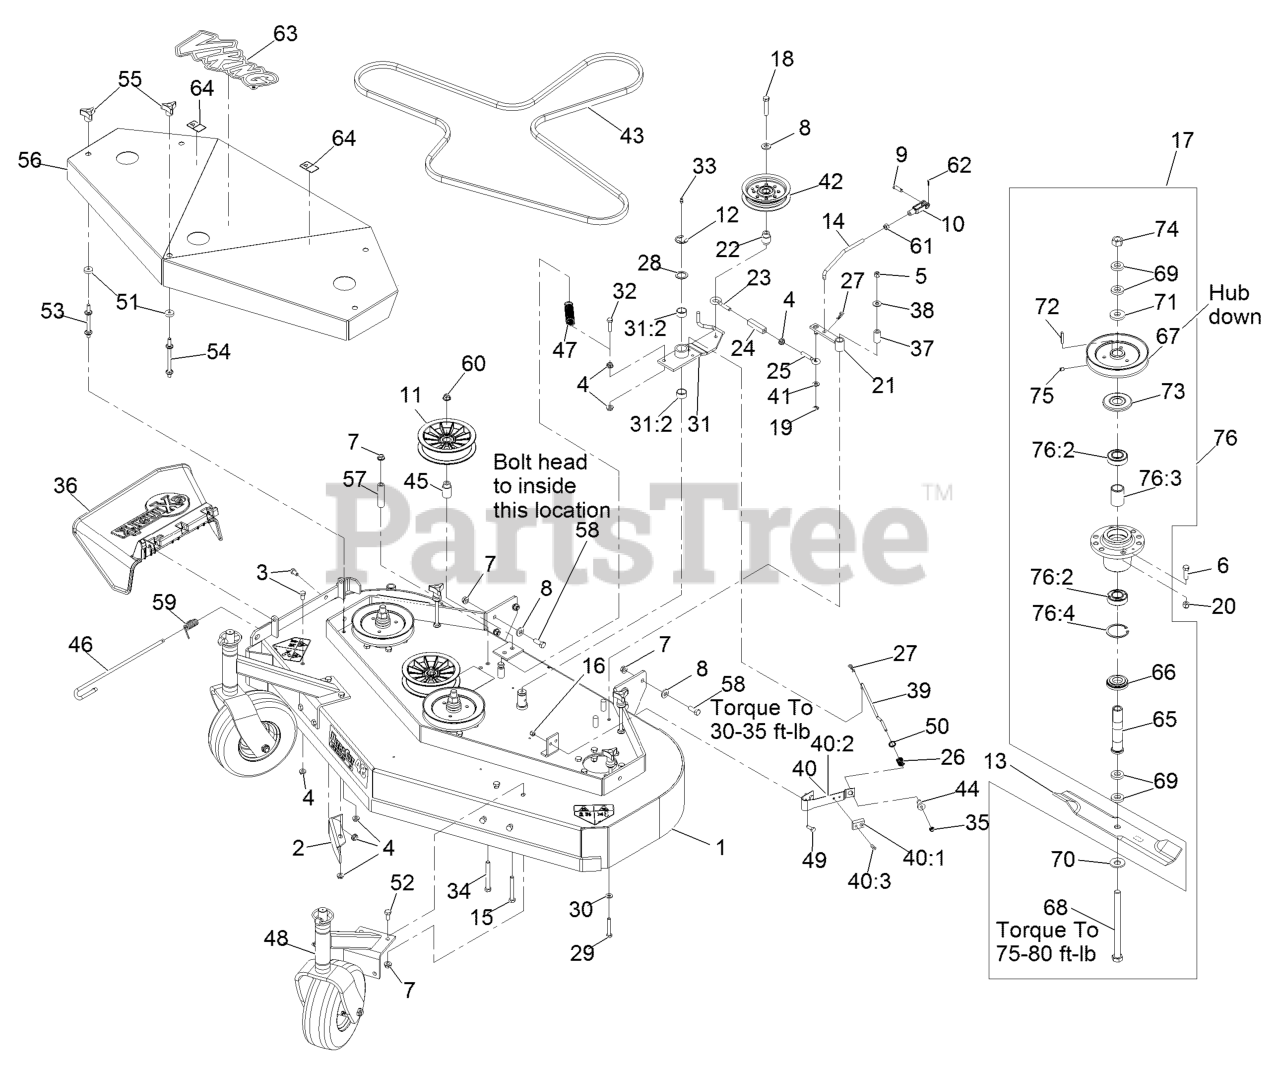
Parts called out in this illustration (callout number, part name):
1	DECK-SERVICE, 48
2	BAFFLE-DOGLEG
3	SCREW-HH
5	NUT-LOCK, NI
6	SCREW-HH
7	NUT-HHF, WHIZ
8	WASHER-BELLEVILLE
9	PIN-CLEVIS
10	YOKE-ADJUSTABLE
11	PULLEY,IDLER 5"
12	RING-RETAINING, EXT
14	ARM-LINKAGE, ASSIST
15	SCREW-HH
16	NUT-LOCK, NI
17	ASM, CUTTER HOUSING OUTER
18	SCREW-HH
19	RING-RETAINING, EXT
20	NUT-LOCK, NI
21	ARM-ASSIST, 32/36
22	BUSHING-ENGAGEMENT
23	EYEBOLT-THREAD, LH
24	BODY-TURNBUCKLE
25	EYEBOLT-THREAD, RH
26	SPRING-COMPRESSION
27	PIN-COTTER
28	WASHER-SPINDLE
29	SCREW-HH
30	WASHER-SPRING
31	IDLER ARM ASM
31:2	SLEEVE-BEARING
32	SCREW-HH, SPECIAL
33	FITTING-GREASE
34	SCREW-HH
35	NUT-LOCK, NI
36	CHUTE DEFLECTOR XRK M056
37	TUBE-PIVOT
38	WASHER-FLAT
39	ROD-BRAKE
40	PAD AND SPRING ASM
40:1	PAD-BRAKE
40:3	RIVET-POP
41	WASHER-PLAIN
43	BELT,BLADE 48
44	SPACER-FLANGED
45	BUSHING-IDLER
46	PIN-CHUTE
47	SPRING-EXTENSION
48	ASM-CASTER MNT W/WEIGHT
49	SCREW-HH
50	RING-PUSH ON
52	SCREW-HH
53	STUD-SHIELD, BELT (SHORT)
54	STUD-SHIELD, BELT (LONG)
55	KNOB-3 PRONG
56	ASM,SHIELD W/DECALS 48 VI
56	Shield-Belt
58	SCREW-HH
59	SPRING, TORSION
60	NUT-HF, NI
61	NUT-HEX
62	PIN-COTTER
63	DECAL,VH MODEL
64	DECAL-WARNING
65	TUBE-SPINDLE, SHORT
66	SPACER-GUARD, BOTTOM
67	SHEAVE
68	SCREW-CAP, HH
70	WASHER-SPRING
71	WASHER-RETAINER, SHEAVE
73	GUARD-BEARING, TOP
74	NUT-HEX
75	SETSCREW
76	Cutter Housing ASM
76	KIT, CUTTER HOUSING
76:2	BEARING-JACKSHAFT
76:3	SPACER-BEARING
76:4	RING-SNAP
